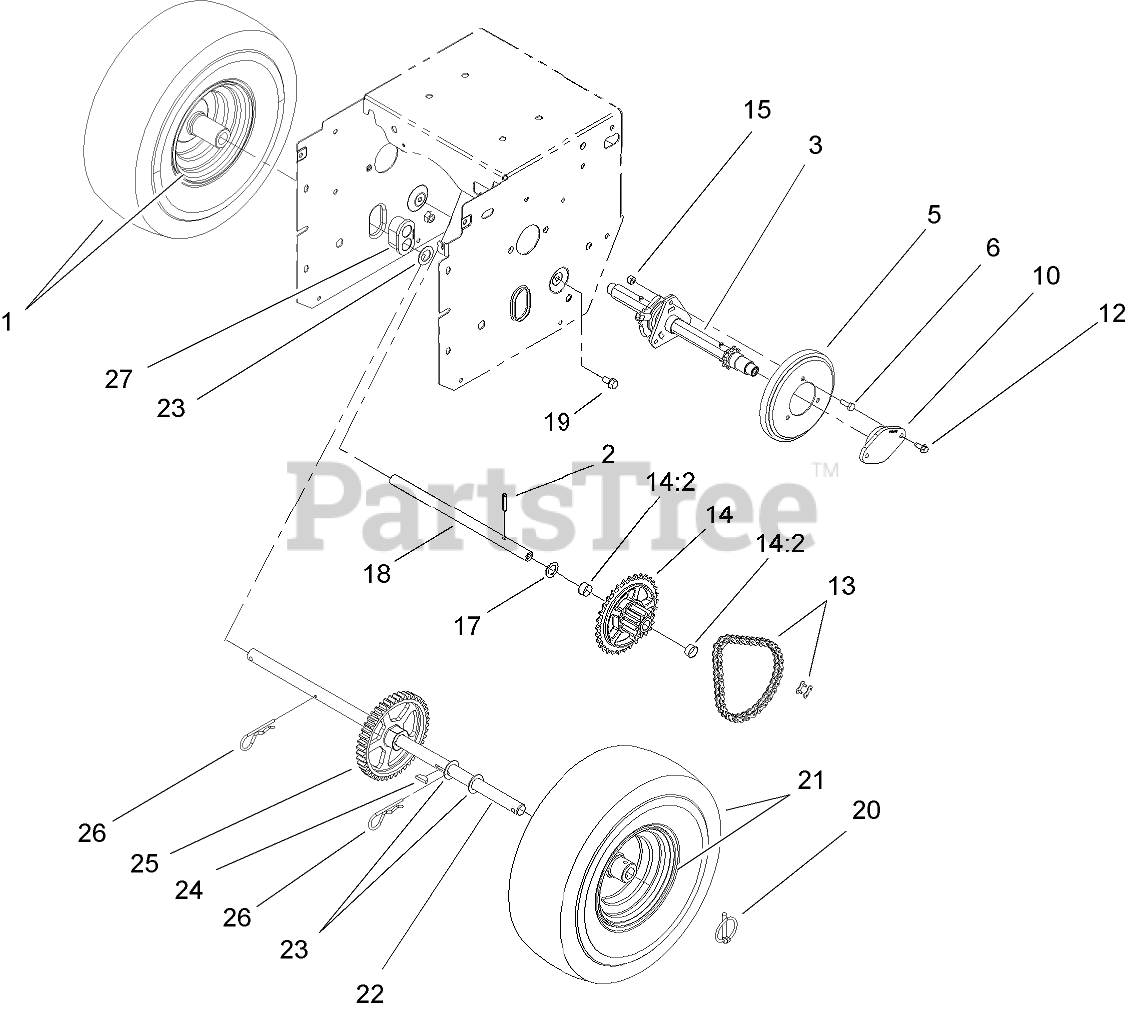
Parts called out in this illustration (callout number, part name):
1	RIM-TIRE
2	PIN-ROLL, SLOTTED
3	HEXSHAFT-ASM
5	WHEEL-FRICTION
6	SCREW-HH
10	RETAINER-BEARING
12	SCREW-HWH
13	CHAIN-ROLLER
13	LINK-CONNECTING
14	SPROCKET ASM
14:2	BUSHING-FLANGE
15	NUT-LOCK, NI
17	WASHER-FLAT
18	SHAFT-INTERMEDIATE
19	SCREW-HWHTF
20	KLIK PIN ASM
21	RIM-TIRE
22	SHAFT-AXLE
23	WASHER-THRUST
24	KEY-WOODRUFF
25	GEAR-AXLE, 44 TOOTH
26	PIN-HAIR
27	BEARING-AXLE
